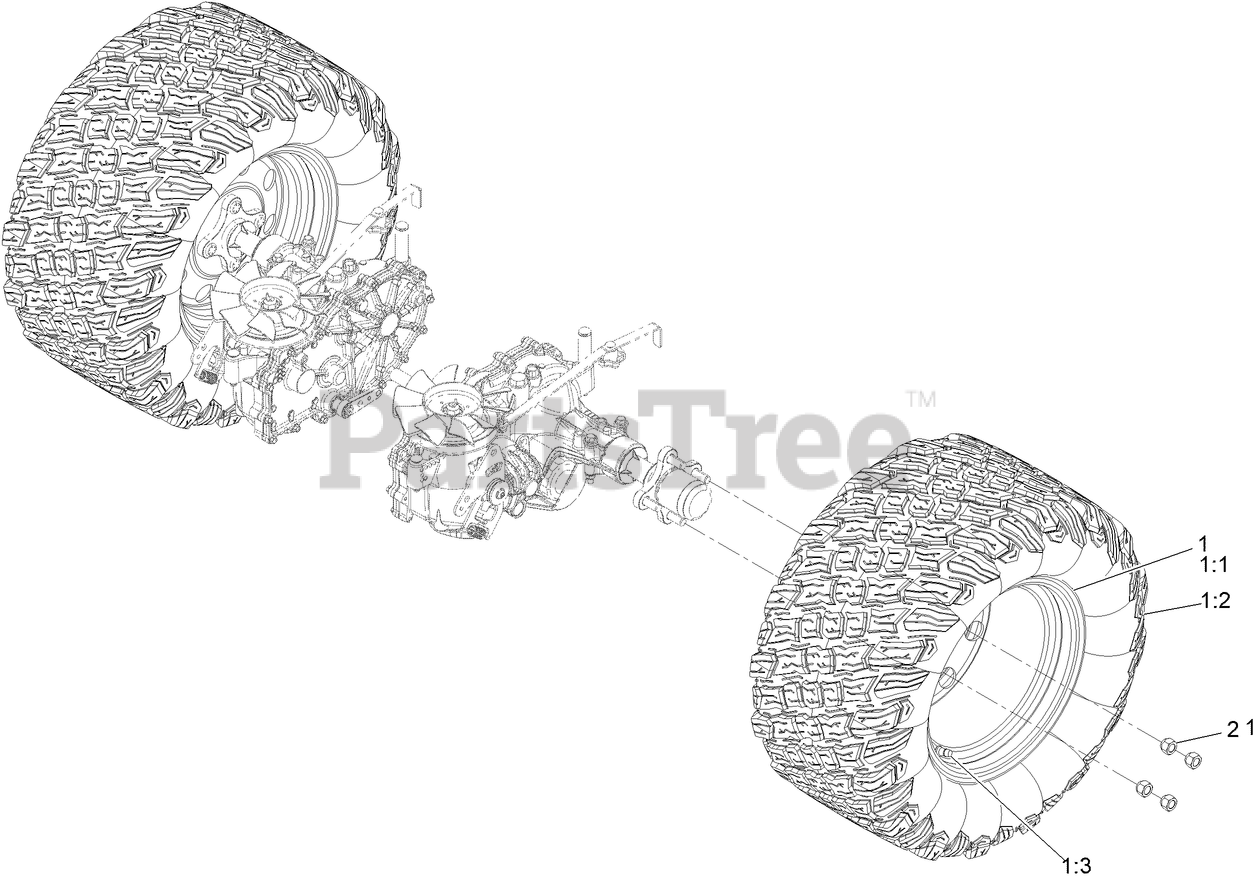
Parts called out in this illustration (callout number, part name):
1	ASM-WHEEL AND TIRE
1:2	Tire-Kenda K3012
1:3	VALVE
2	NUT-LUG
